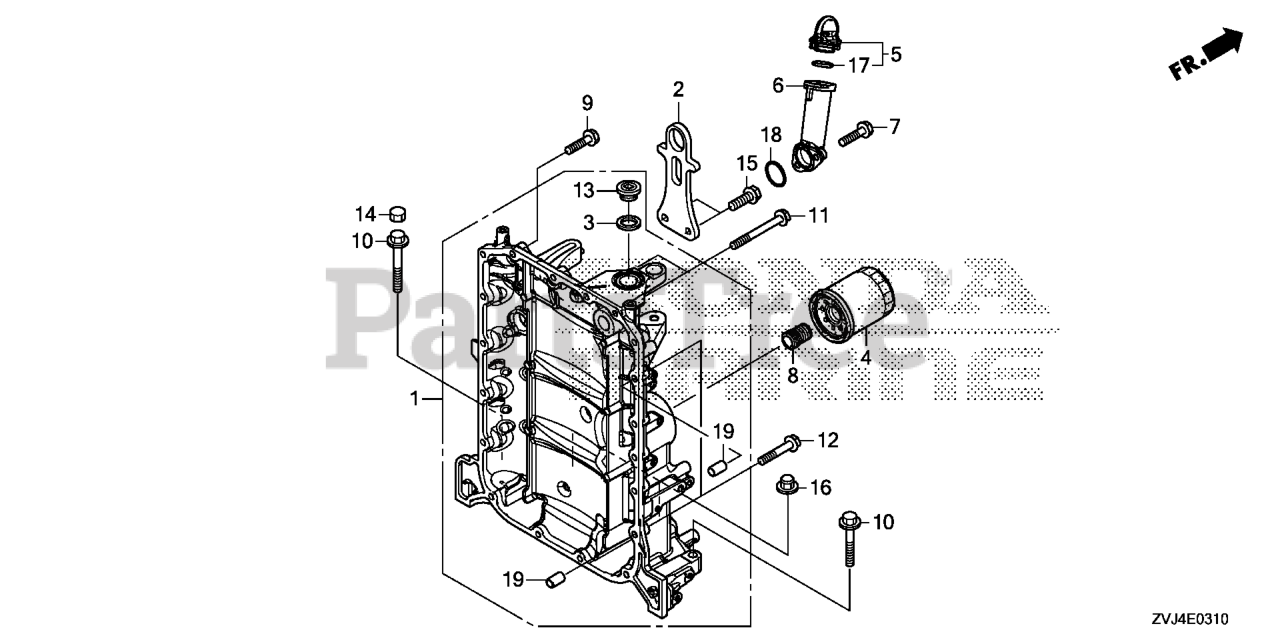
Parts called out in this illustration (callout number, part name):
1	CRANKCASE COMP
2	HANGER, ENGINE
2	HANGER, ENG
3	WASHER, SEALING (22MM)
4	FILTER, OIL
5	CAP ASSY., OIL FILLER
6	EXTENSION, OIL FILLER
7	BOLT, FLANGE (6X25)
8	HOLDER, OIL FILTER
9	BOLT, FLANGE (6X32)
10	BOLT, FLANGE (10X55)
11	BOLT, FLANGE (6X55)
12	BOLT, FLANGE (6X37)
13	BOLT, SEALING (22MM)
14	CAP, BOLT (10MM)
15	BOLT, FLANGE (8X25)
16	NUT, FLANGE CAP (10MM)
16	NUT (10MM)
17	O-RING (18.1X3.6)
18	O-RING (28.3X2.4) (NOK)
19	PIN A, DOWEL (8X14)
